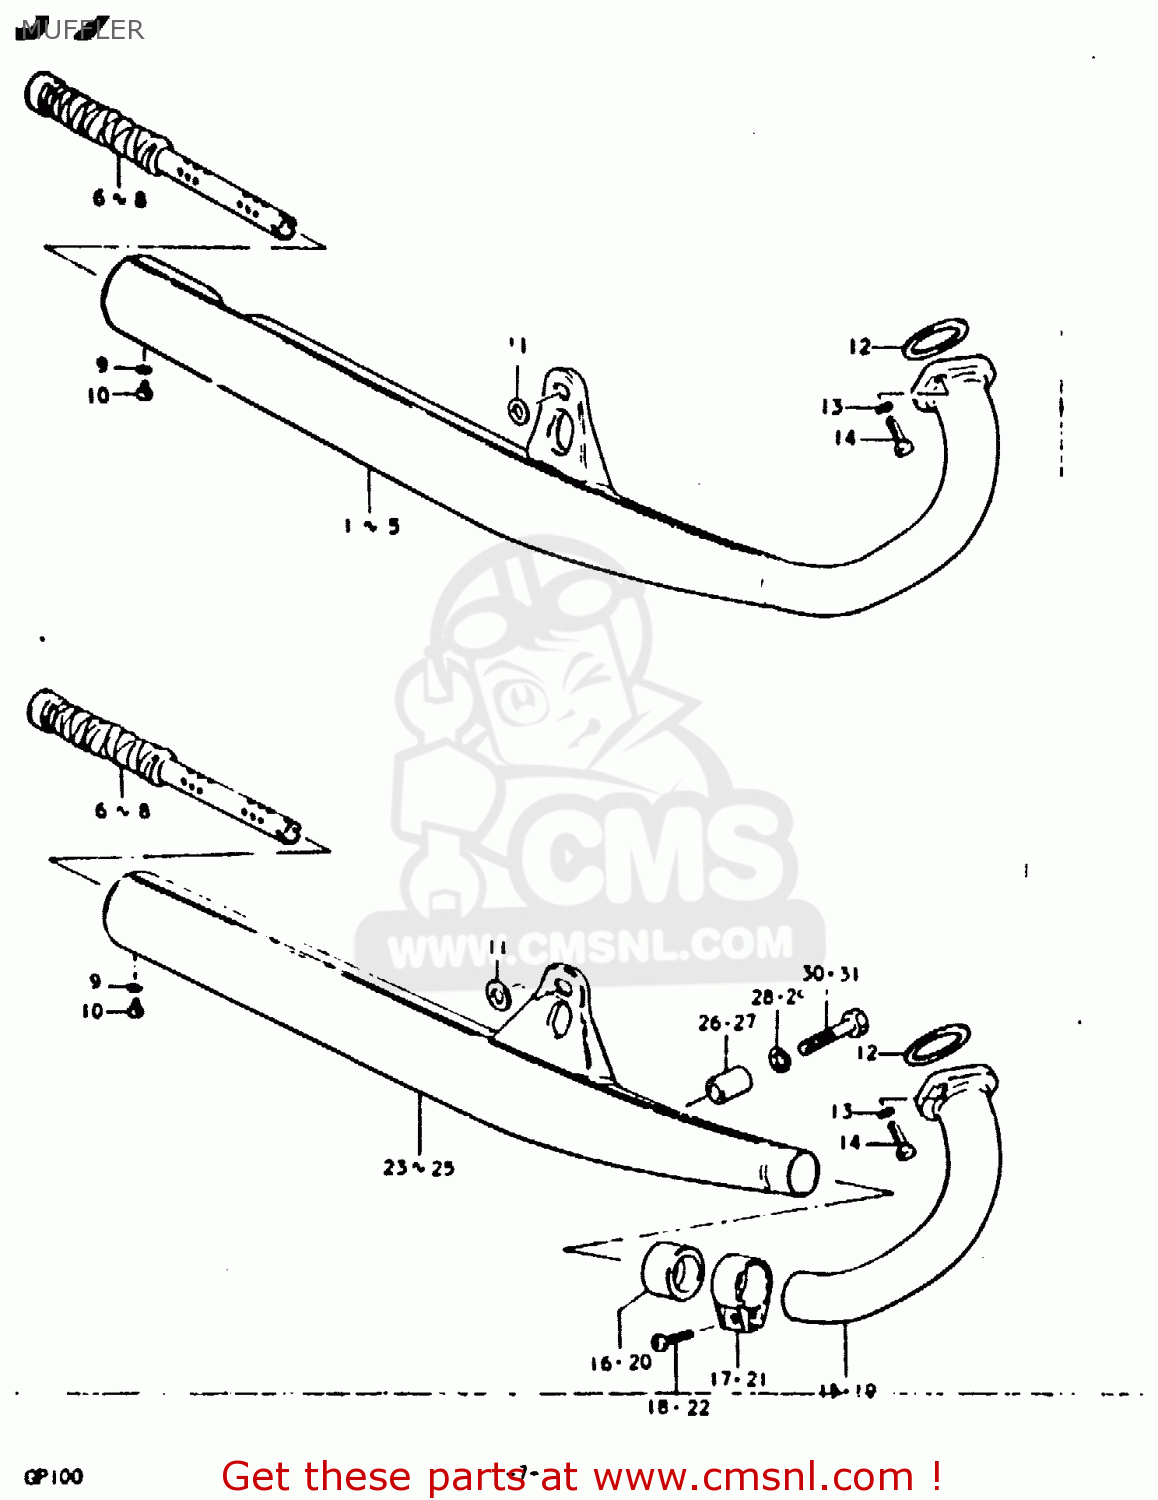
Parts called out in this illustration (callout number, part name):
1	MUFFLER ASSY (TO 14301-39632)
6	PIPE, BAFFLE
9	LOCK WASHER
10	BOLT(5X8)
11	WASHER (12.5X24X3.2)
12	GASKET,EXHAUST PIPE (NAS)
13	LOCK WASHER
14	BOLT
